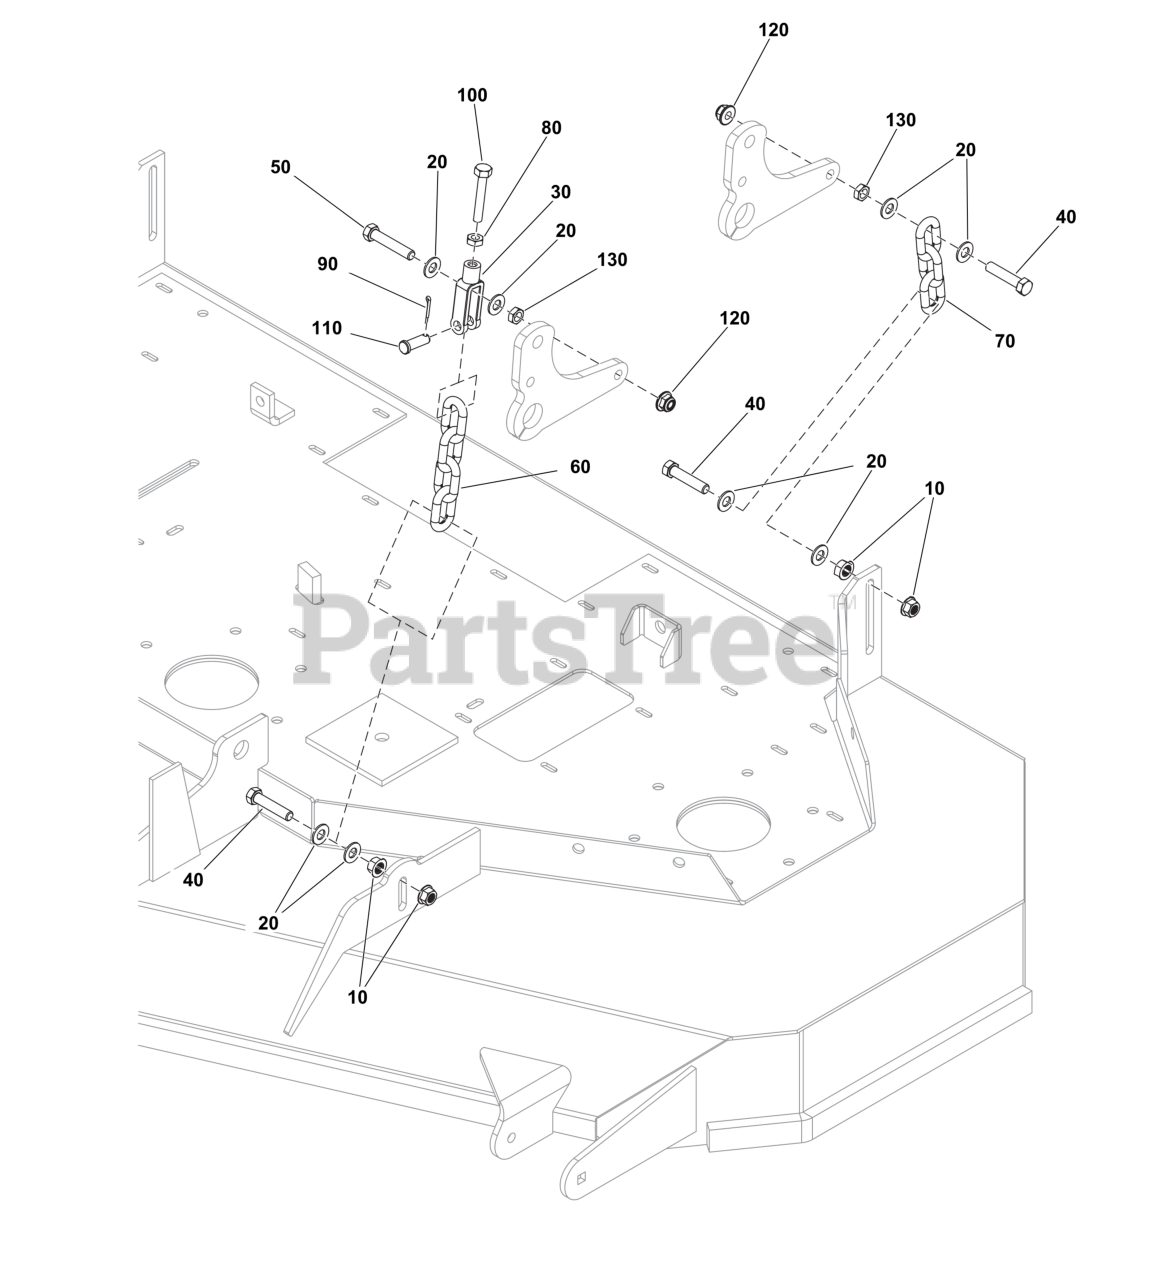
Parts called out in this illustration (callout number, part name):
10	NUT, 3/8-16 HEX SERRA
30	CLEVIS, 5/16-18, 3/8
40	BOLT, 3/8-16 X 1-3/4"
50	CAPSCREW, 3/8-16X2
60	CHAIN, 5/16", 4 LINKS
70	CHAIN, 5/16" GD30, 3
80	NUT, 5/16-18 HEX JAM
90	PIN, COTTER, 3/32X.75
100	BOLT, 5/16-18X2
120	NUT, 3/8-16 HEX NYLOCK
130	NUT, 3/8-16 HEX JAM
